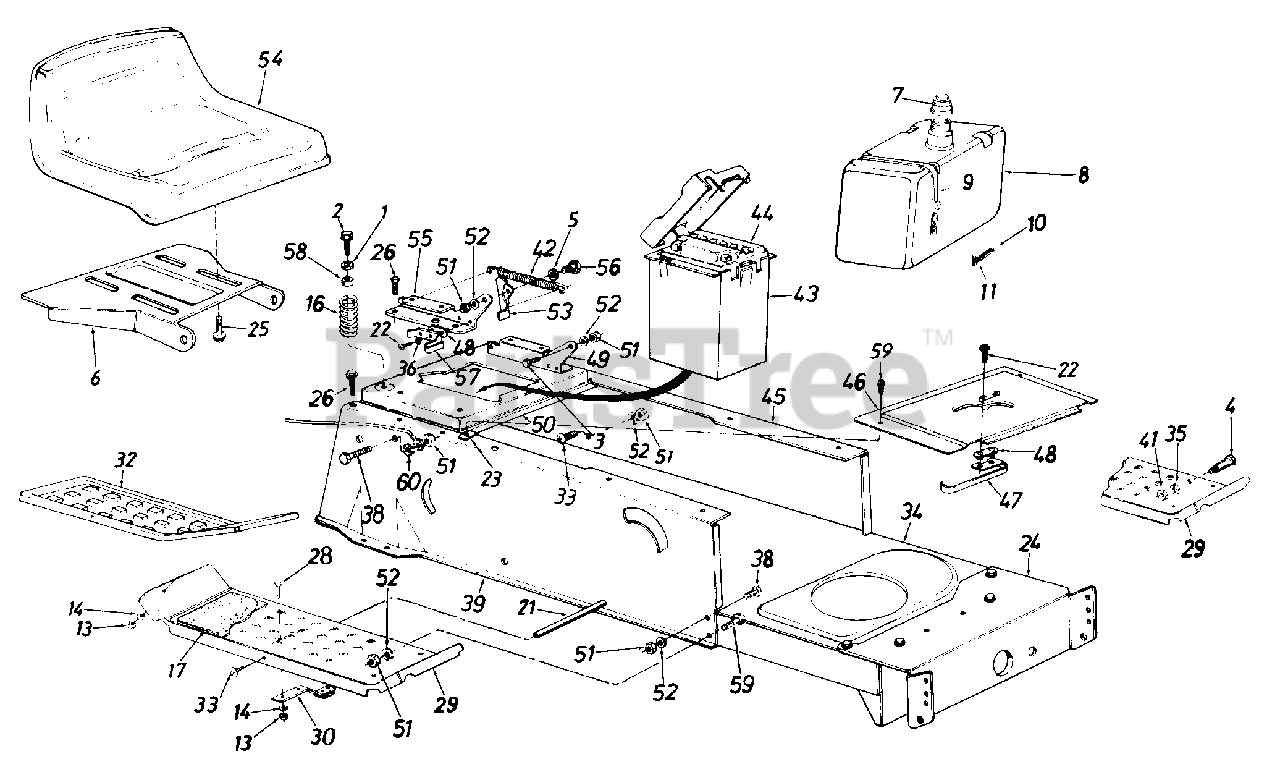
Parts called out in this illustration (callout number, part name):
1	Fl-Wash. .344" I.D. x .875"
2	Hex Wash. Hd. Tap Scr. 5/16-18 x 1.0" Lg.
3	Shld. Bolt .437" Dia. x .162
4	Shld. Bolt .50" Dia. x .84"
5	Spr-Wash. .445" I.D. x .75
6	Seat Pivot Bracket
7	Fuel Cap Gauge
8	Fuel Tank
9	Tie Strap
10	Fuel Line
11	Hose Clamp
13	Hex Nut 1/4-20 Thd.
14	L-Wash. 1/4" I.D.
16	Compression Spring
17	Foot Pad
21	Running Board Rod
22	Hex Wash. Hd. AB-Tap Scr. #8 x .50" Lg.
23	Speed Nut #10Z
24	Front Pivot Brkt.
25	Hex Tap Scr. 3/8-16 x .75"
26	Hex Wash. Hd. AB-Tap Scr. 5/16 x .75" Lg.
28	Carriage Bolt 1/4-20 x .62"
29	Running Board
30	Blade Brake Ass'y.
32	Rubber Foot Pad-L.H.
33	Truss Mach. Scr. 5/16-18 x .75" Lg.
34	Lower Frame
35	L-Wash. 3/8" I.D.
36	Fiber Wash.
38	Hex Bolt 5/16-18 x 75n Lg.
42	Extension Spring 5.31" Lg.
43	Battery Box w/Cover
44	12-V Battery
47	Reverse Safety Switch
48	Insulator Nut Plate
49	Seat Pivot Brkt. Support-L.H.
50	Hitch Plate
51	Hex Nut 5/16-18 Thd.*
52	L-Wash. 5/16" I.D.
53	Seat Lift Brkt.
54	Seat 8-7/8" High
55	Seat Pivot Brkt. Support-R.H.
56	Shld. Bolt .437" Dia. x .268"
57	Spring Switch
58	Bushing
59	Truss Hd. Scr. 5/16-18 x 1.0" Lg.
60	External L-Wash. 5/16" I.D.
